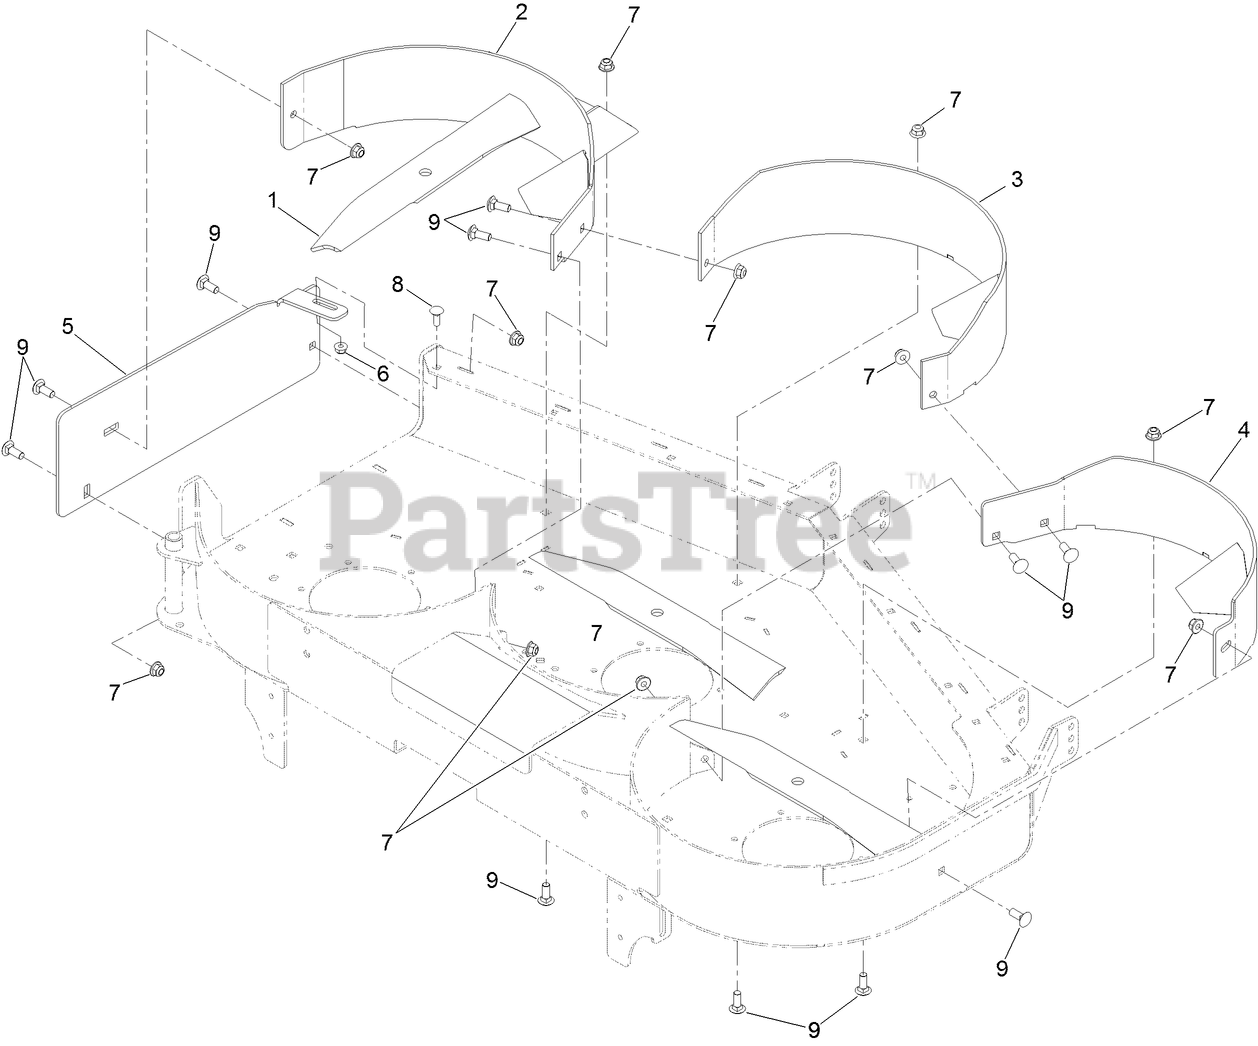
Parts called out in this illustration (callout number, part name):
1	BLADE-ROTARY, RECYCLING 16.5IN
2	BAFFLE-RH
3	BAFFLE-CENTER
4	BAFFLE-LH
5	PLATE-COVER, DISCHARGE
6	NUT-HF, NI
7	NUT-HF, NI
8	SCREW-CARR
9	BOLT-CARR
